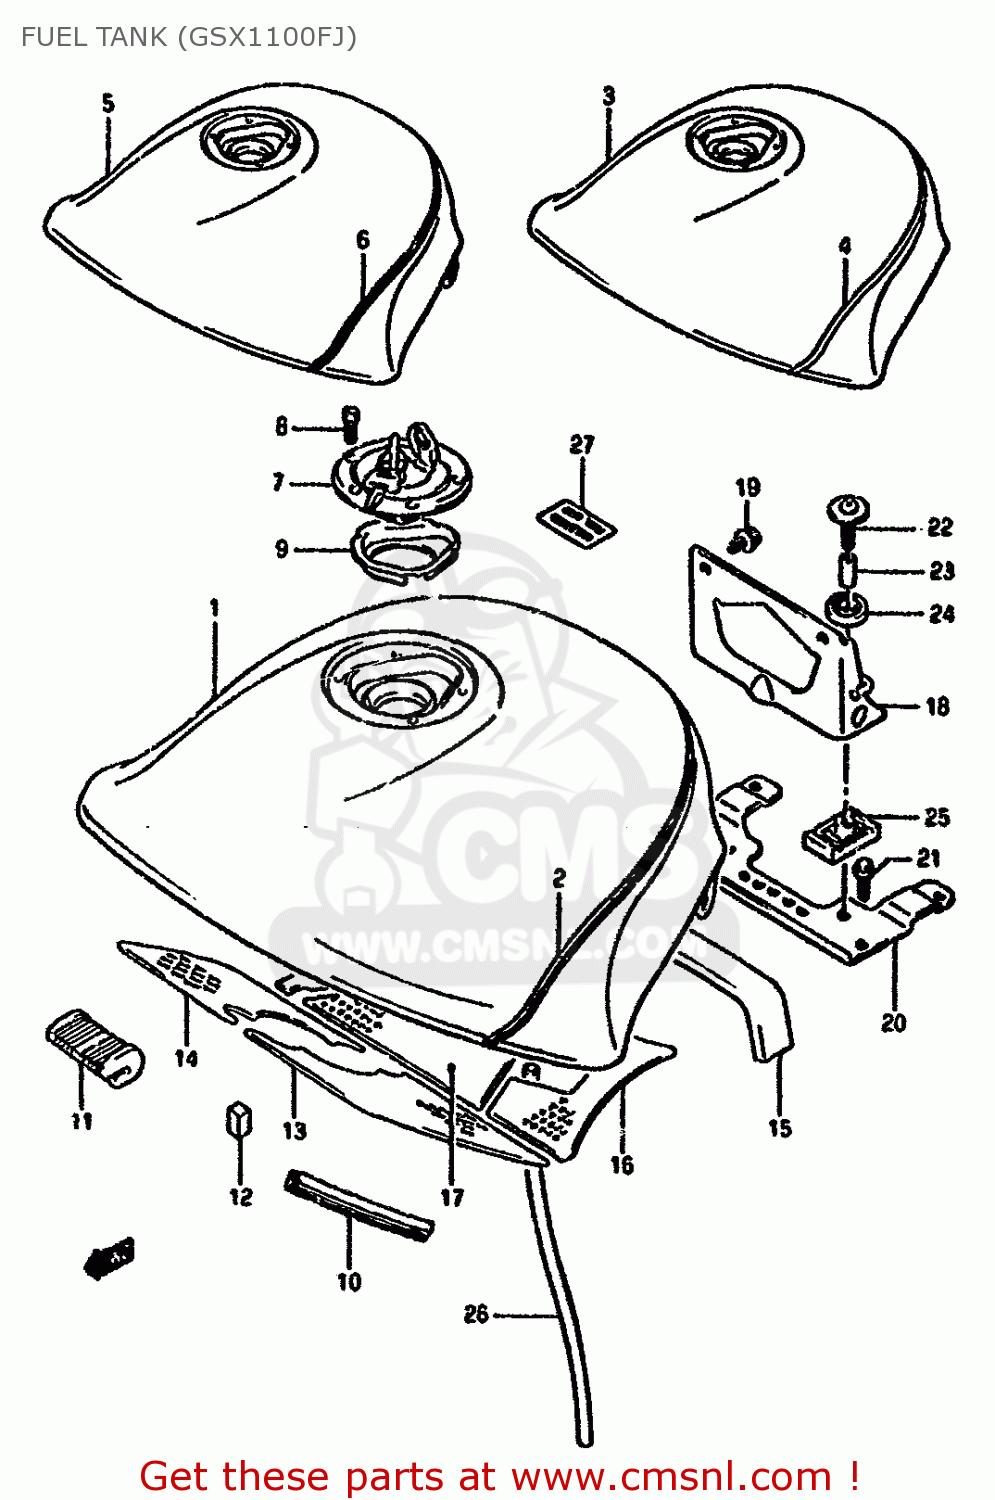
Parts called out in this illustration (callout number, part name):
1	TANK ASSEMBLY,FUEL
2	TAPE SET,FUEL TANK
3	TANK ASSY,FUEL (BLUE/RED)
4	TAPE SET,FUEL TANK
5	TANK ASSY,FUEL (RED/WHITE)
6	TAPE SET,FUEL TANK
7	CAP SET,FUEL TANK
8	BOLT(5X10)
9	COVER,FUEL TANK INLET
10	MOLDING,FUEL TANK
11	CUSHION,FUEL TANK FR
12	CUSHION,FUEL TANK SIDE
13	HEATSHIELD,FUEL TANK FR,L
14	HEAT SHIELD,FUEL TANK
15	HEAT SHIELD,FUEL TANK
16	HEATSHIELD,FUEL TANK RR,L
17	HEAT SHIELD,FUEL TANK
18	BRACKET COMP,FUEL TANK
19	SCREW(6X16)
20	BRACKET,FUEL TANK RR LOW
21	SCREW, CENTER
22	BOLT L:35,WITH WASHER
23	SPACER (6.4X9X21.5)
24	CUSHION
25	CUSHION
26	HOSE
27	LABEL,FUEL CAUTION
